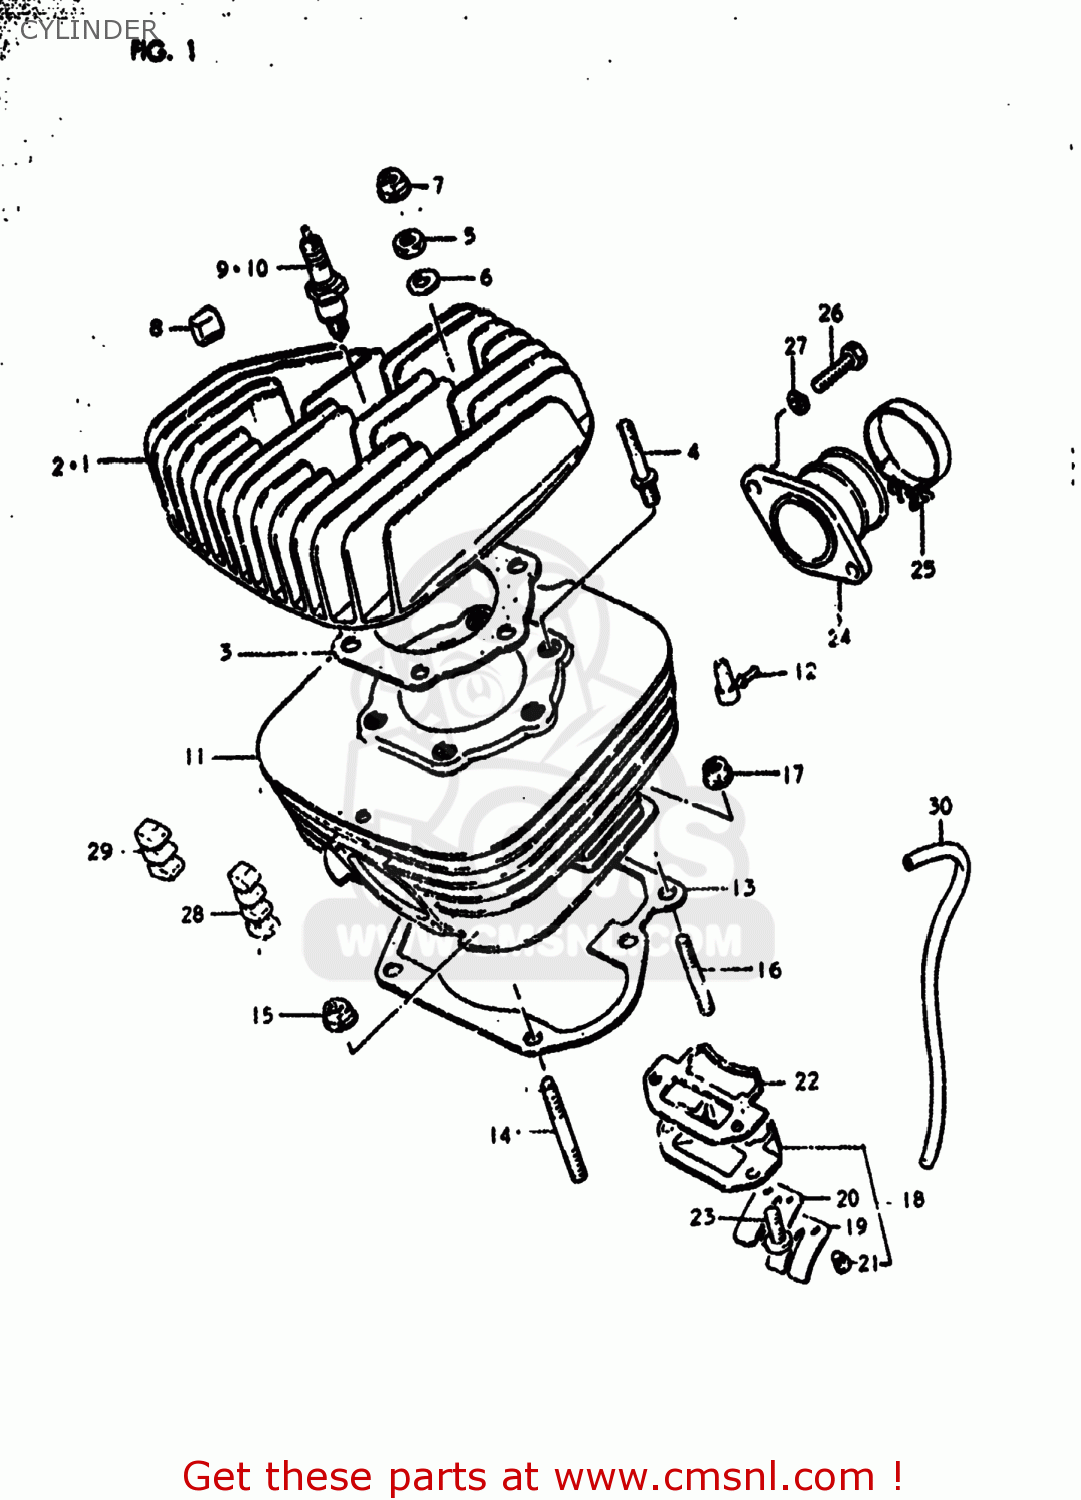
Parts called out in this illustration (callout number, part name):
1	HEAD,CYLINDER
2	HEAD,CYLINDER
3	GASKET,CYLINDER HEAD (MCA)
4	BOLT,STUD
5	NUT (8MM)
6	WASHER
7	NUT
8	PAD,CYLINDER
9	PLUG,SPARK(B7HS)
10	SPARK PLUG B7ES
11	CYLINDER
12	UNION,OIL HOSE
13	GASKET,CYLINDER (MCA)
14	STUD 10X25
15	NUT
16	STUD 8X25
17	NUT
18	VALVE ASSY,REED
19	STOPPER,REED VALVE
20	VALVE,REED
21	SCREW,REED VALVE
22	GASKET,REED VALVE (MCA)
23	SCREW
24	PIPE,INTAKE
25	CLAMP
26	BOLT
27	LOCK WASHER
28	PAD,CYLINDER
29	PAD,CYLINDER
30	HOSE
